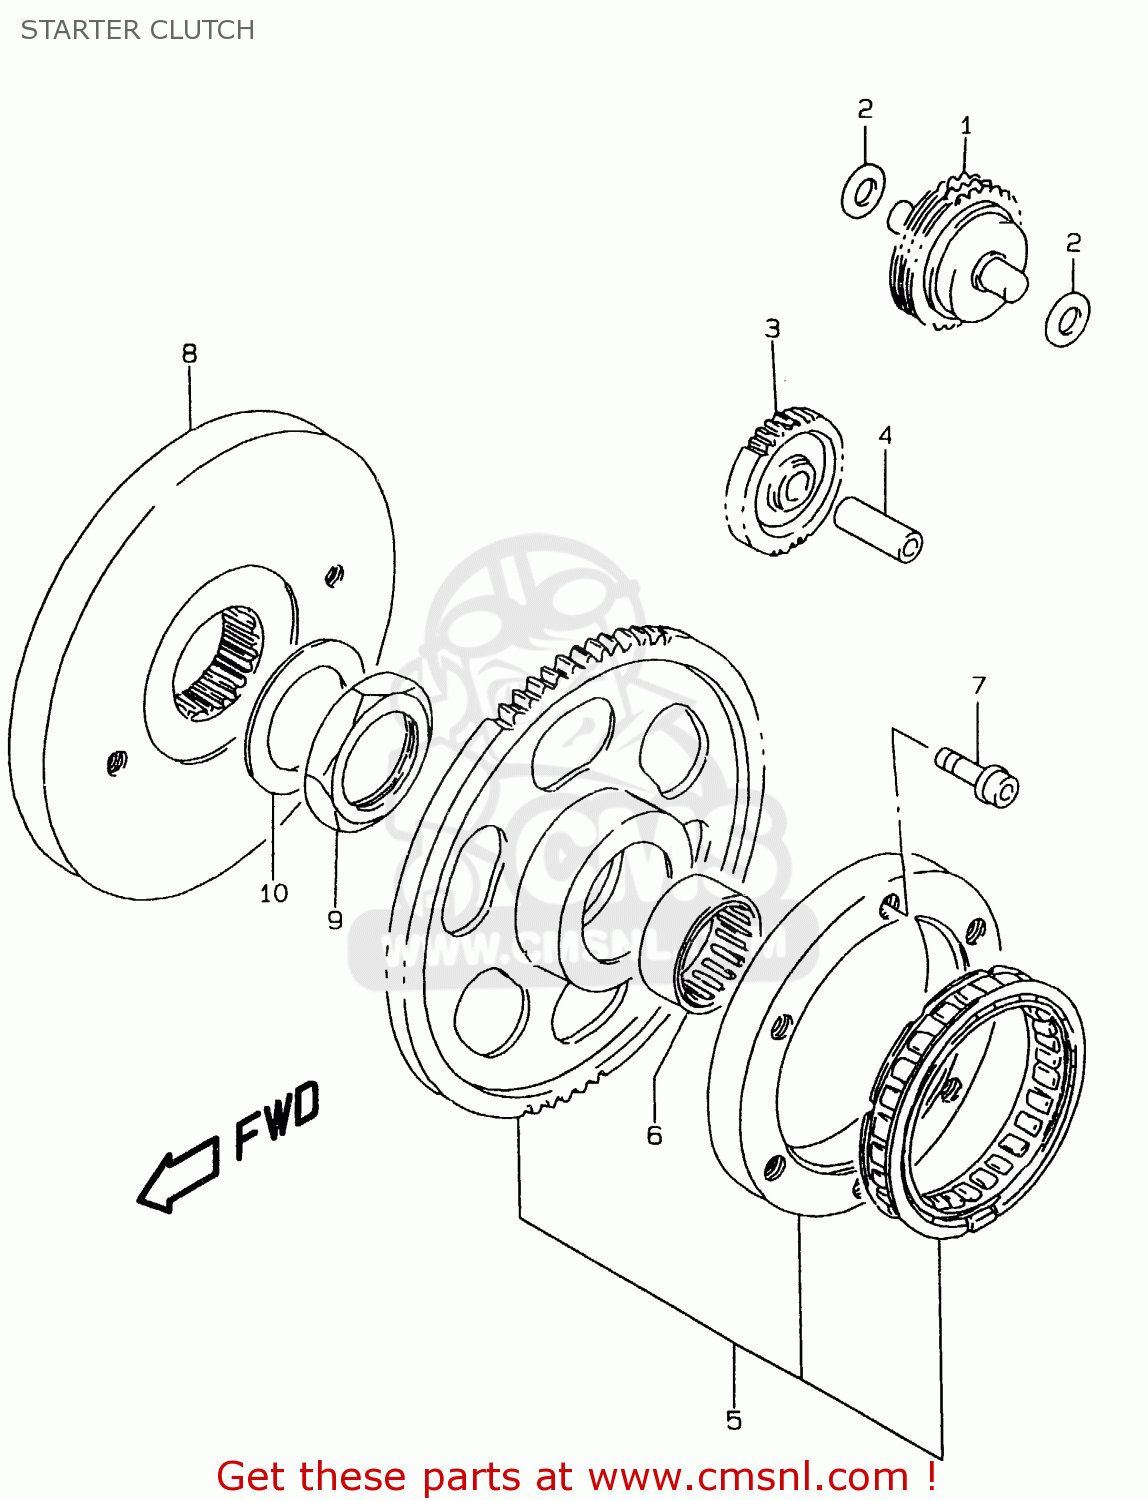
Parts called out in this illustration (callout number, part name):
1	LIMITER ASSEMBLY,STARTER IDLER GEAR
2	WASHER,THRUST
3	GEAR,STARTER IDLE NO.2
4	PIN(10X30)
5	CLUTCH SET,STARTER
6	BEARING(31X39X17.8)
7	BOLT
8	FLYWHEEL
9	NUT,FLYWHEEL
10	WASHER
